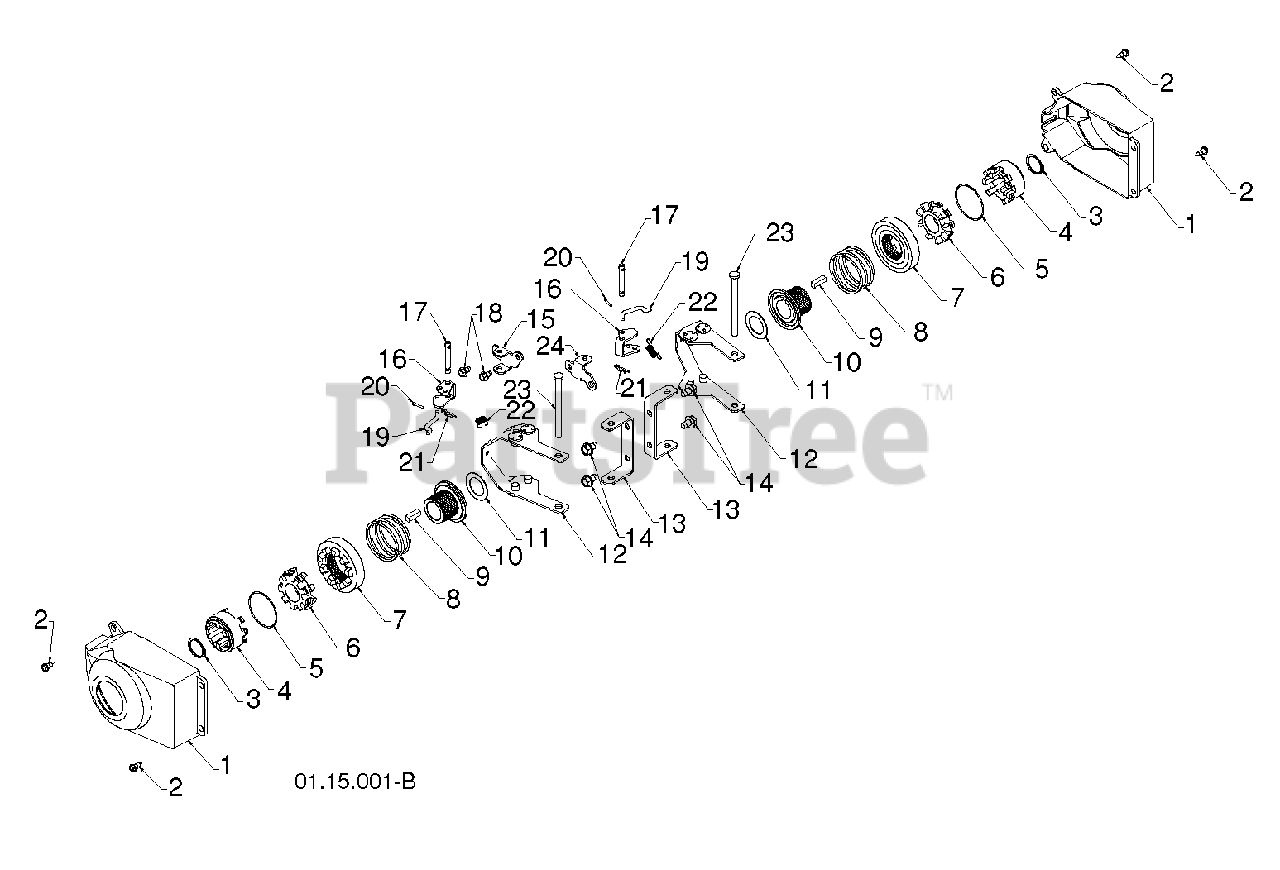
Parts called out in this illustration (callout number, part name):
1	COVER, POWER STEERING
2	SCREW, HEX HEAD, TAPPING
4	DRIVER WHEEL
5	RING, WIRE RETAINER
6	LOBE WHEEL
7	SLIDE.CLUTCH
8	SPRING, CLUTCH SLIDE
9	KEY, SQUARE 1/4 X .875
10	LOBE.AXLE
11	WASHER 1.00
12	STEERING YOKE
13	BRACKET.STEER.PNT.BLACK
14	SCREW LT
15	BRKT.STEER.PIVOT.RH
16	BELLCRANK.STEER
17	PIN, STEERING BELLCRANK
19	LINK.STEER.YOKE
20	RETAINER CLIP
21	RETAINER CLIP PM
22	SPRING LATCH
23	PIN, STEERING LEVER
24	CONTROL SHAFT
